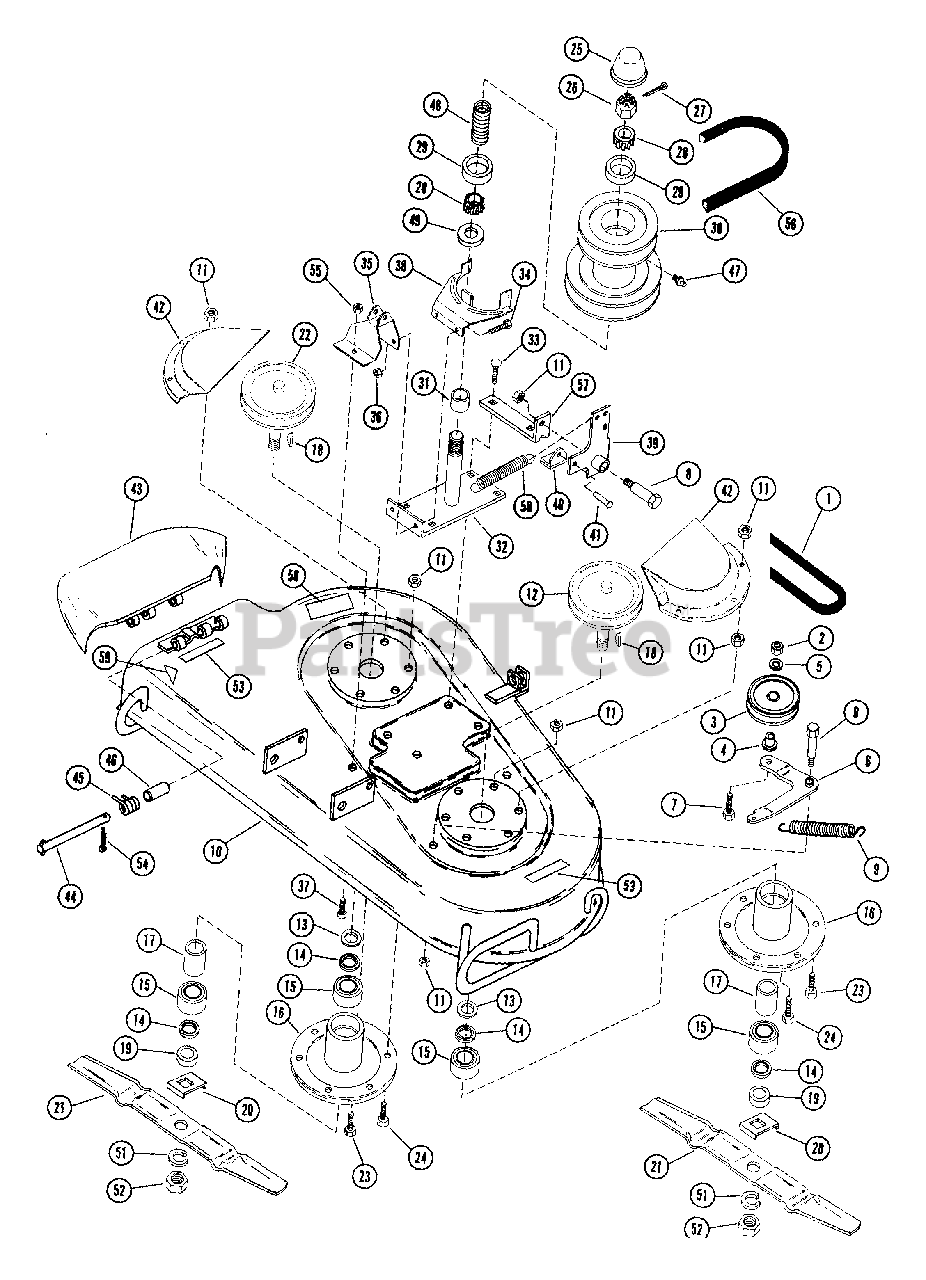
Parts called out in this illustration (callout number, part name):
1	V-BELT, 4L-RAW EDGE
2	NUT-LK-CTR .50-13
3	IDLER-FLAT 2.75X.62
4	BSHG-FLG .500X.625X.500X.750
5	WSHR-FL-STL .505X.880X.072 PL
7	BLT-HEX .50-13X1.25 PL GR2
8	SHOULDER BOLT
9	SG-TENS .091X.73X5.28 WLD 30
10	PAN ASSEMBLY
11	NUT-LK-CTR .375-16 GR A PL
13	WSHR-FL-STL .755X1.250X.125
14	BEARING SLINGER
15	BRG-BALL .751X1.78X.61
16	SPINDLE HOUSING
17	SPACER .753X1.000X1.140
18	KEY-WDRF .188X.75X.313 SAE 9
19	RETAINER HUB
20	BLADE TRAY
21	MOWER BLADE
22	SHEAVE
23	BLT-HEX .38-16X1.00 PL
24	BLT-HEX .38-16X.75 PL GR2
25	CAP, GREASE
26	NUT-JAM SL .75-20 PL
27	PIN-COTR .12 X 1.25 PL
28	BRG-CONE .750X.61
29	BRG-CUP 1.781X.475
30	SHEAVE ASSEMBLY-MOWER
31	SPACER .753X1.000X.625
33	BLT-RDHDSQNK .38-16X.75 SHT PL
34	BLT-SERHFWH .31-18X.75 PL
35	BRACKET
36	NUT-FLG. .312-18 PL
37	BLT-HEX .31-18X.50 PL GR2
41	RVT .25X.50 RH ST
43	PAN CHUTE EXTENSION
44	CLEVIS PIN
45	SG-TORS .095X.50X 1.0
46	BSHG-SLV .334 X .502 X 1.437
47	HYDRAULIC DRIVE FITTING
48	SG-COMP .091X.950X2.062
49	SEAL .750X1.690X.153
50	SG-TENS .072X.50X8.0 WLD 25
51	WSHR-LK .750X.188 MED PL
52	NUT-JAM .75-10 PL
53	WARNING LABEL
54	PIN-COTR .09X.75 PL
55	NUT-LK .312-18 GR A PL
56	V-BELT, 5L-RAW EDGE
57	BRACKET
58	MOWER CAUTION LABEL
59	SAFETY LABEL
